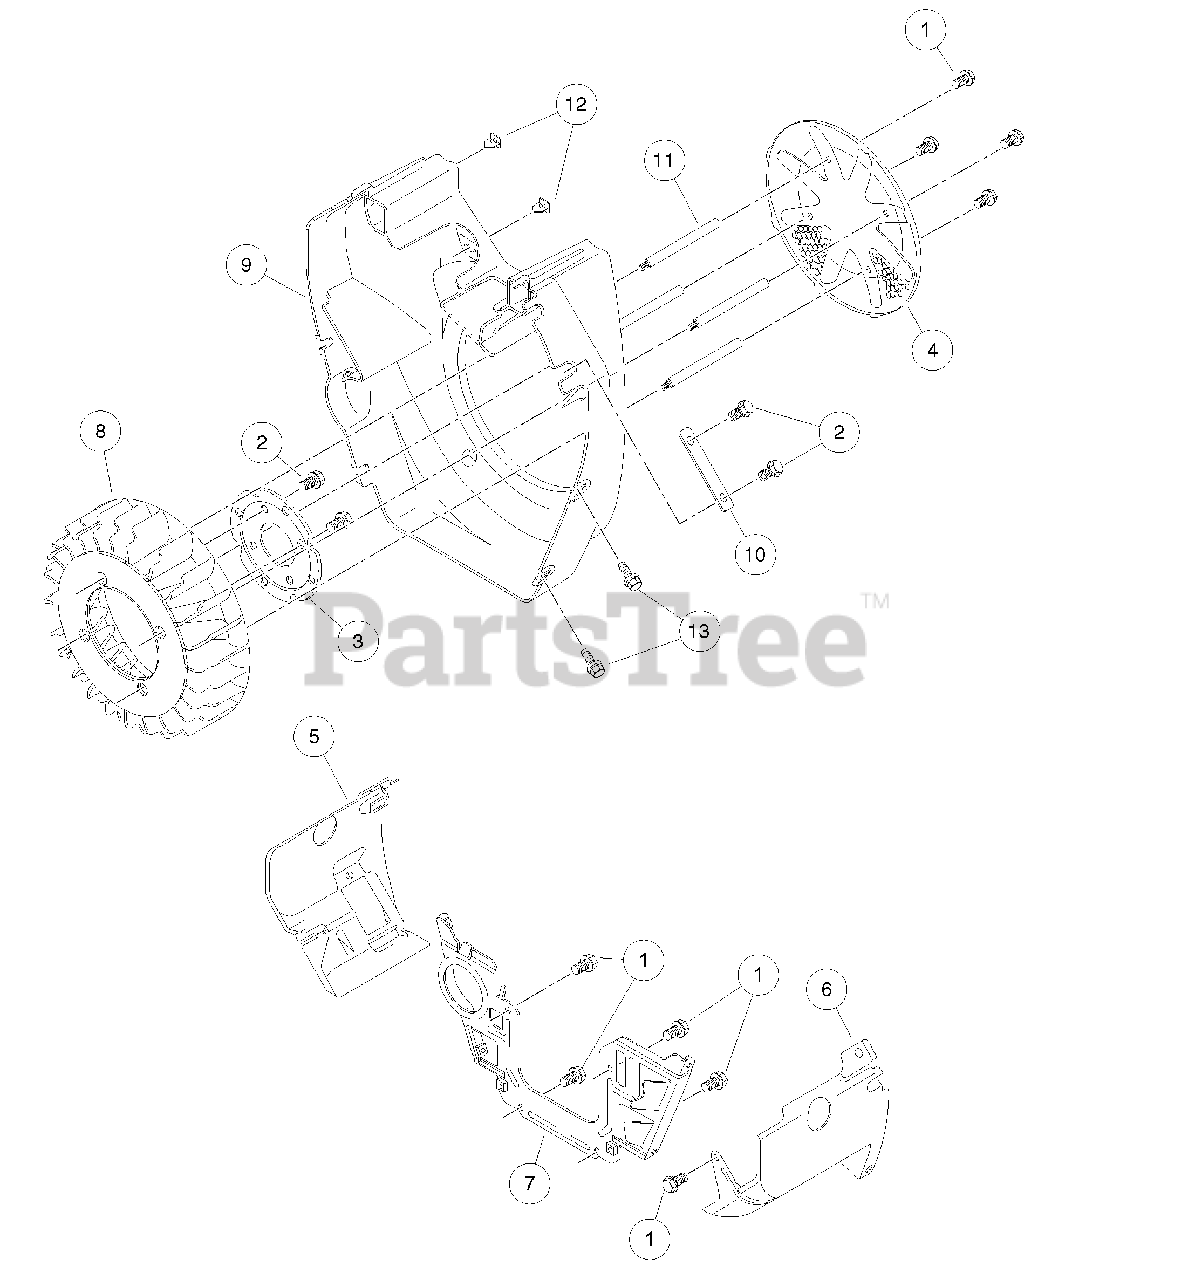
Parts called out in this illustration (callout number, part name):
1	Bolt, Flg, M6 X 1.0 X 12
2	Bolt, Flg, M6 X 1.0 X 16
3	Plate, Housing, Fan, Fh
4	Screen, Fan, Fh
5	Shroud, Engine, Rh, Fh
6	Shroud, Engine, Lh, Fh
7	Shroud, Engine, Front, Fh
8	Fan, Cooling, Fh
9	Housing, Engine, Fh
10	Washer, Housing, Fan, Fh
11	Stud, Fan Screen, Fh
12	Nut, Press In, Front Cover, Fh
13	Bolt, Oil Pickup, Fh
